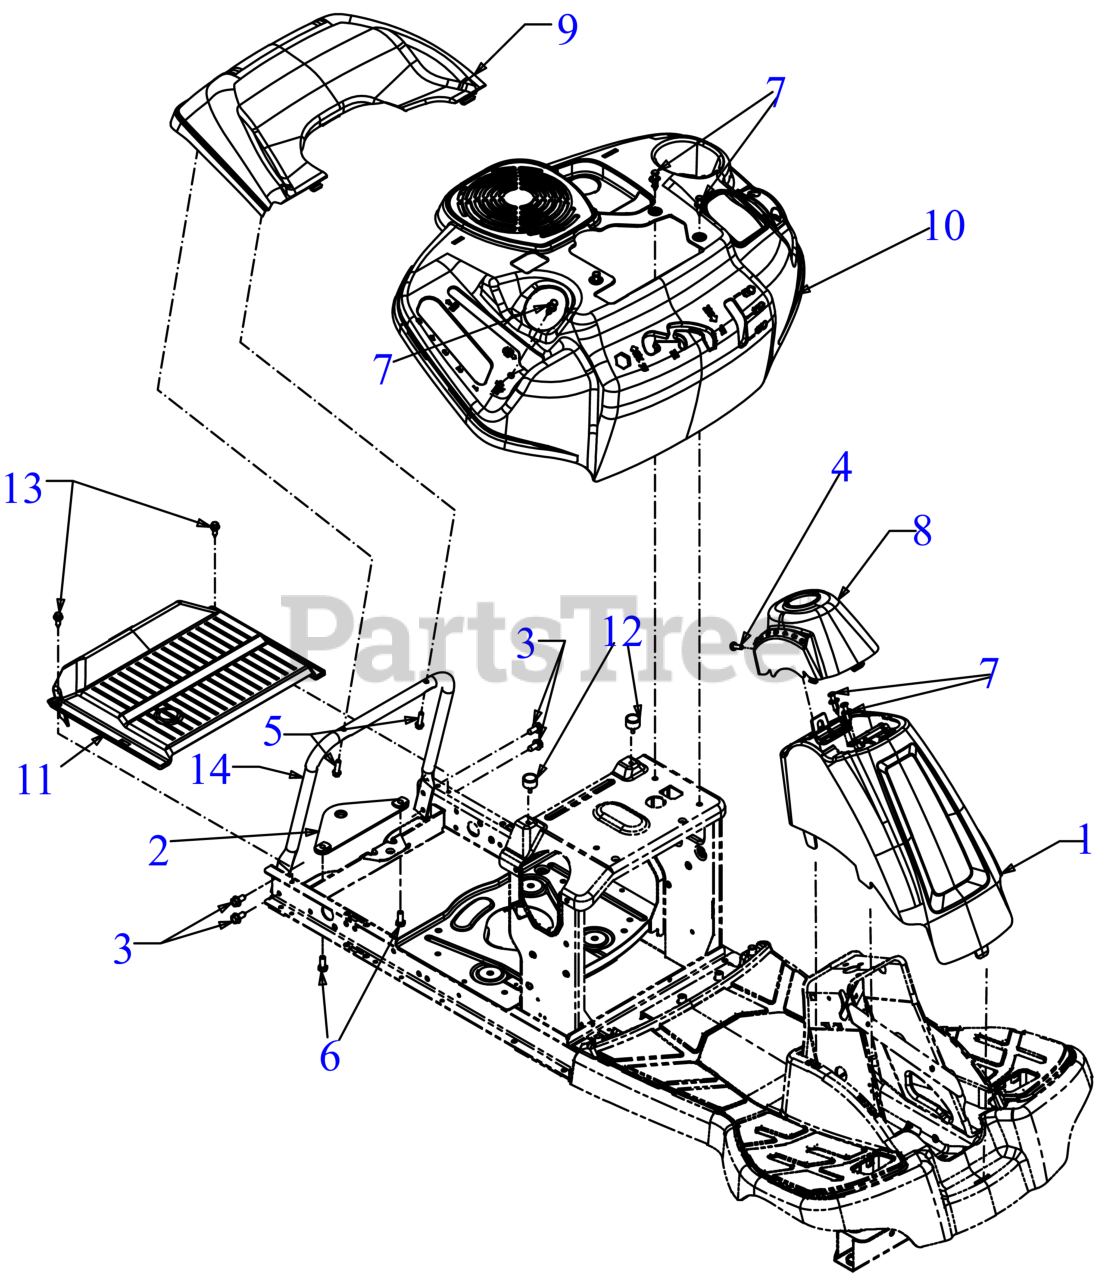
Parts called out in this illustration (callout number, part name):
1	COLUMN COVER ASSEMBLY (ORANGE)
3	SCREW 5/16-18 x .750
4	SCREW 1/4-20X.75
5	SCREW 1/4-15 x 1.00
6	SCREW 5/16-18 x .625
7	PLASTIC RIVET
8	STEERING COLUMN CAP
9	REAR COVER
10	FENDER (ORANGE)
11	CVT DRIVE COVER
12	BUMPER .62 DIA x .50
13	SHOULDER SCREW
